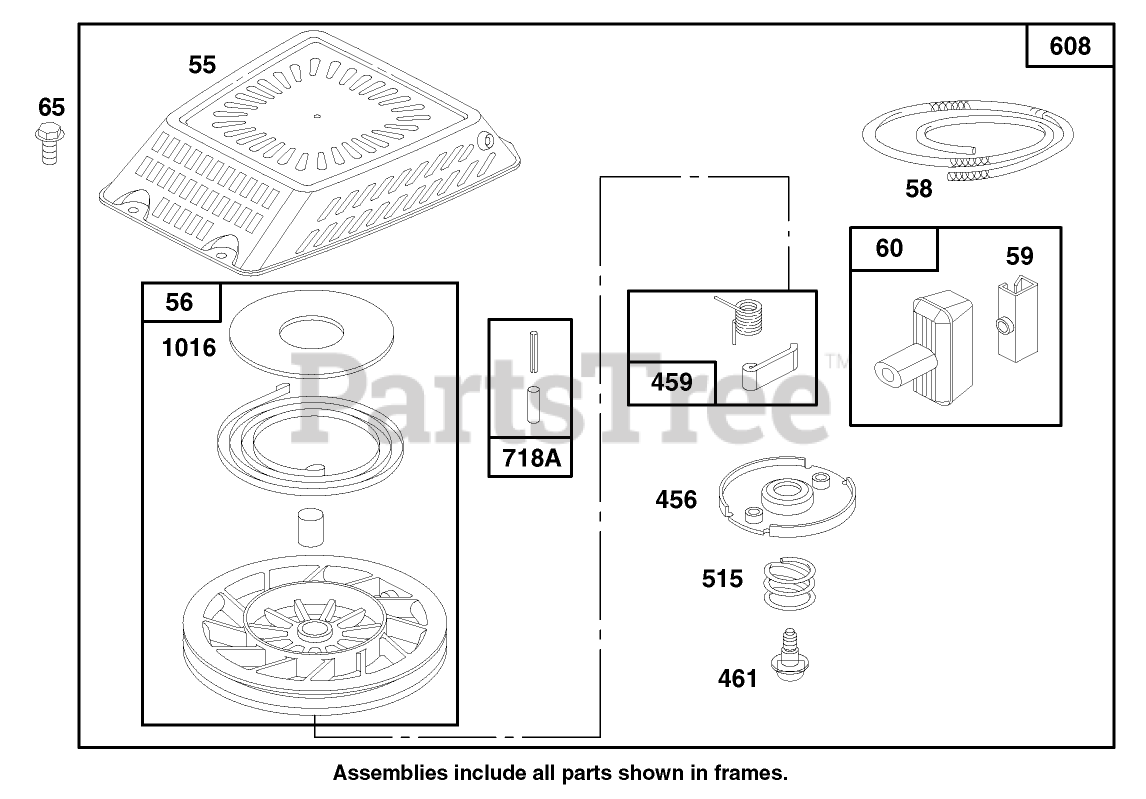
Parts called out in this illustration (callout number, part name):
59	INSERT-HANDLE, REWIND
456	RETAINER - SPRING
515	SPRING - RETAINER
